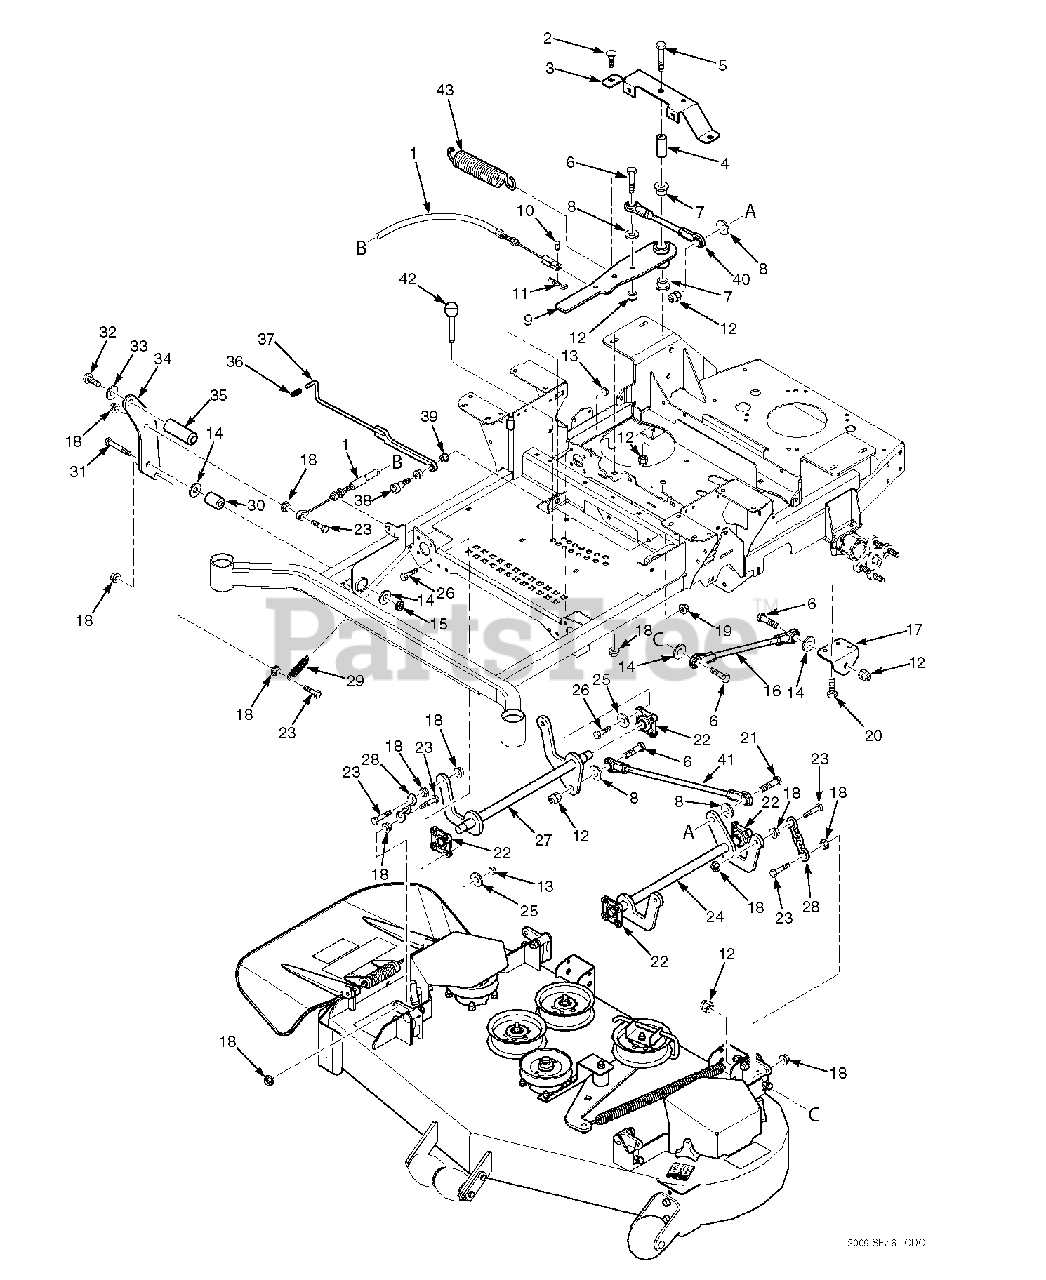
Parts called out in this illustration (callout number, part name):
1	Cable, Deck Lift
2	Bolt, Carriage 3/8-16 x 3/4"
3	Support, Idler Arm
4	Spacer, Deck Lift Pivot
5	Bolt, Hex Head 1/2-13 x 3-3/4"
6	Bolt, Hex Head 1/2-13 x 1-3/4"
7	Bearing
8	Flatwasher, 1/2-.531 x 1.06 x .095
9	Deck Lift Bellcrank Assembly
10	Clevis Pin, 5/16 x 3/4"
11	Hair Pin, .094 x 1.62"
12	Nut, Elastic Stop 1/2-13
13	Nut, Elastic Stop 5/16-18
14	Flatwasher, 1/2-.562 x 1.375 x .109
15	Nut, Center Lock 1/2-13
16	Linkage, Push Arm
17	Bracket, Push Arm Link
18	Nut, Serrated Flange 3/8-16
19	Nut, Elastic Stop 3/8-16
20	Bolt, Hex Head 5/16-18 x 3"
21	Bolt, Hex Head 1/2-13 x 2-1/2"
22	Bearing, Deck Lift
23	Bolt, Hex Head 3/8-16 x 1-1/2"
24	Weldment, Deck Lift LH
25	Flatwasher, 1/4-.312 x .750 x .065
26	Bolt, Hex Head 5/16-18 x 1"
27	Weldment, Deck Lift RH
28	Chain, Deck lift
29	Spring, Deck Lift
30	Sleeve, Deck Lift Pivot
31	Bolt, Hex Head 1/2-13 x 3"
32	Bolt, Head Socket 5/8-11 x 1-1/2"
33	Lockwasher, 5/8 Spring
34	Pedal, Foot Bracket
35	Foot Pedal
36	Grip, Deck Latch
37	Weldment, Deck Latch
38	Bolt, Shoulder 1/2 x 1/2
39	Bearing
40	Linkage Assembly, Deck Lift
41	Linkage Assembly, Deck Lift
42	Pin, Height Adjuster
43	Spring, Deck Lift
